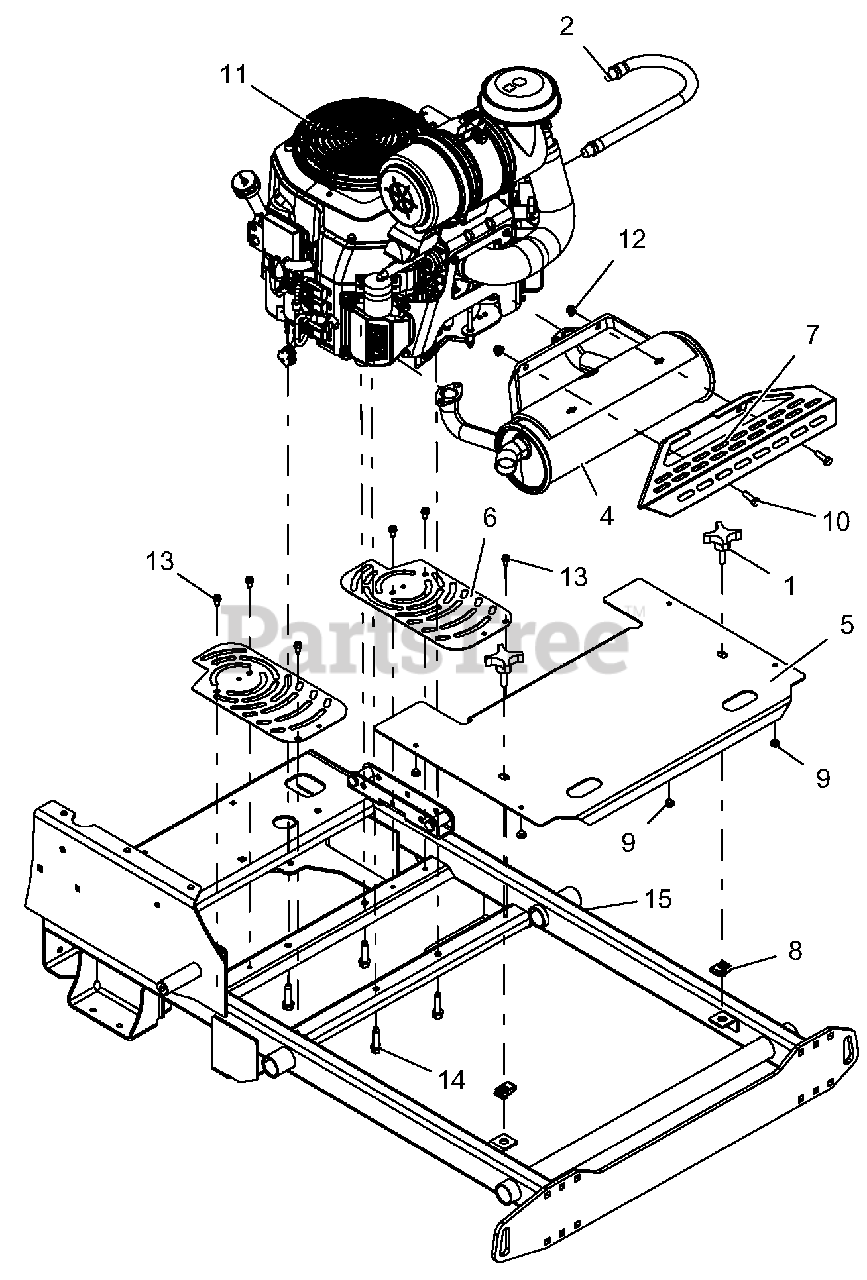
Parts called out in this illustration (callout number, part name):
1	KNOB, 3/8 x 1.25 - 4 PRONG
2	DRAIN, M20 OIL
4	MFLR, KOHLER
5	SHIELD, FRONT PRO-STANCE - RED
6	GUARD, FAN
7	GUARD, HEAT SHIELD - BLACK
8	NUT, RTNR .375-16 x .37
9	BUMPER GROMMET .125 x .25 REV
10	BLT-HEX .31-18 x 1.00 GR5 YWZC
11	ENGINE, KOHLER EFI ECV730
12	NUT-LK-NYL-FLG .31-18 YWZC
13	SCR-TAP .25-20 x .50 HWH TR YWZ
14	SCR-TAP .38-16 x 1.50 HWH TR YZ
15	WLDMT, FRAME PROSTANCE
